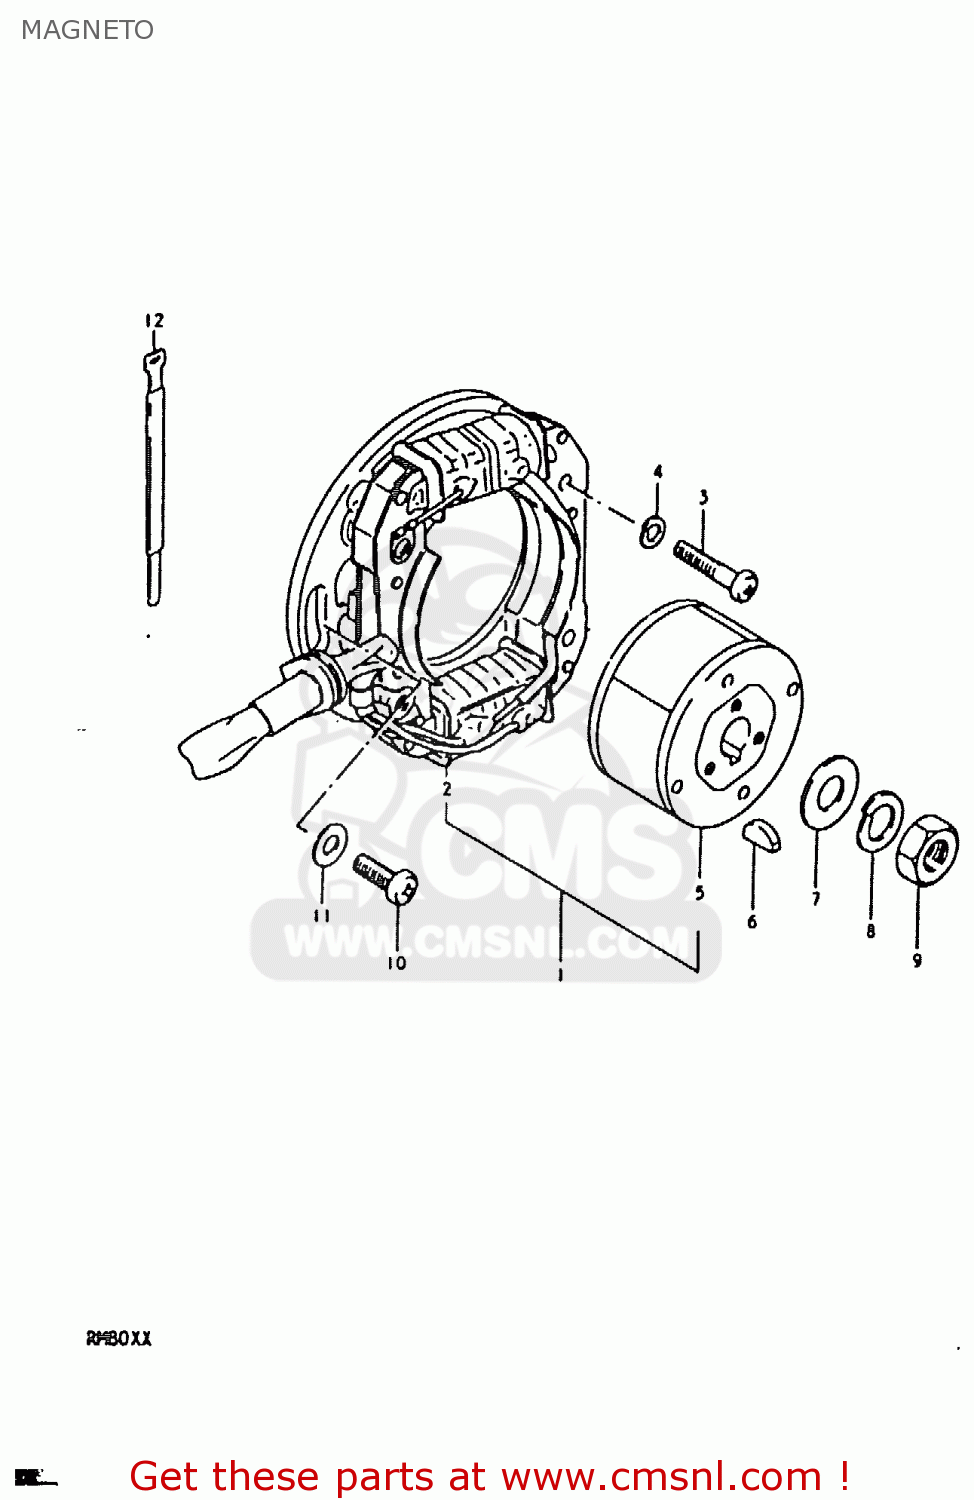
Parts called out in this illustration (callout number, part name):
1	MAGNETO ASSEMBLY
2	STATOR ASSEMBLY
3	SCREW 5X20
4	LOCK WASHER
5	ROTOR ASSEMBLY
6	KEY 4MM
7	WASHER
8	LOCK WASHER
9	NUT (10MM)
10	SCREW
11	WASHER
12	CLAMP
